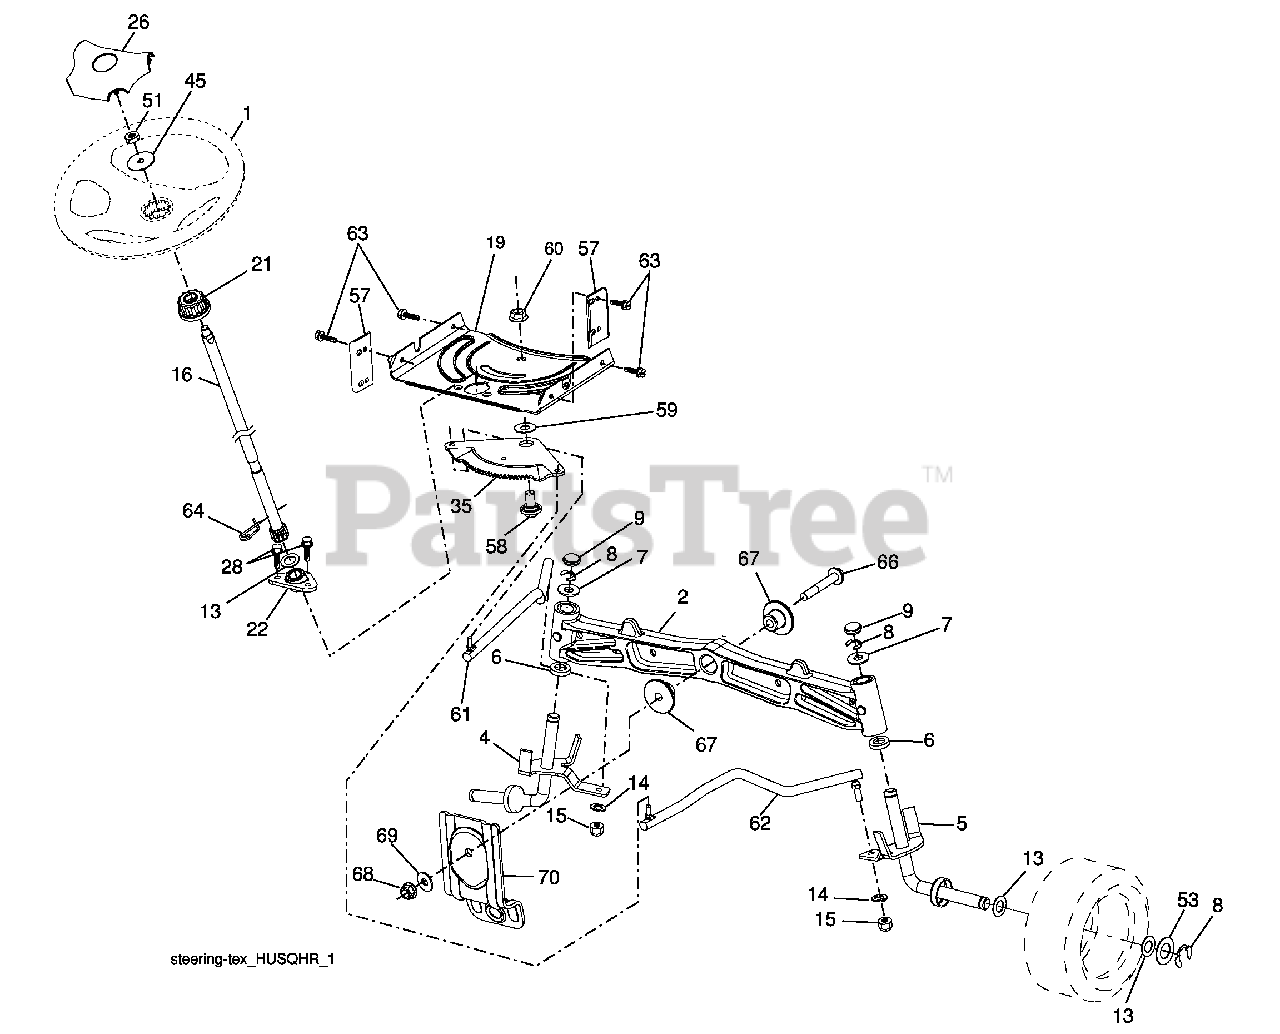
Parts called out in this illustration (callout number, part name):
1	Wheel, Steering
2	Axle Asm., Front
4	Spindle Asm., LH
5	Spindle Asm., RH
6	Bearing, Race Thrust Harden
7	Washer 25/32 x 1-5/8 x 16 Ga.
8	Ring, Clip #T5304-75
9	Cap, Spindle
13	Washer 25/32 x 1-1/4 x 16 Ga.
14	Washer, Lock Hvy Hlcl Spr 3/8
15	Nut, Crown Lock 3/8-24 unf
16	Shaft Steering
19	Plate Steering
21	Adapter, Wheel Steering
22	Steering Supt. Lower
26	Insert, Wheel Steering
28	Screw 3/8-16 x 3/4
35	Gear, Sector Plate
45	Washer 9/16 x 2-3/8 x 12 Ga.
51	Nut Hex Jam Toplock 1/2-20 unf
53	Washer Hardened .793 x 1.637 x .060
57	Bracket Upstop
58	Bolt Shoulder Sector Pivot CFM
59	Washer Thrust Sector Steering
60	Nut Flange Lock 5/8-11
61	Draglink, LH
62	Draglink, RH
63	Screw 5/16-18 x 3/4
64	Retainer Clip Spring Steering
66	Bolt Hex Fghd 7/16-14 x 3 Serr
67	Bushing PM Front Axle
68	Nut Lock Flange 7/16-14 Gr. 5
69	Washer 1.5 x .505 x .118
70	Bracket Deck Susp. Front
